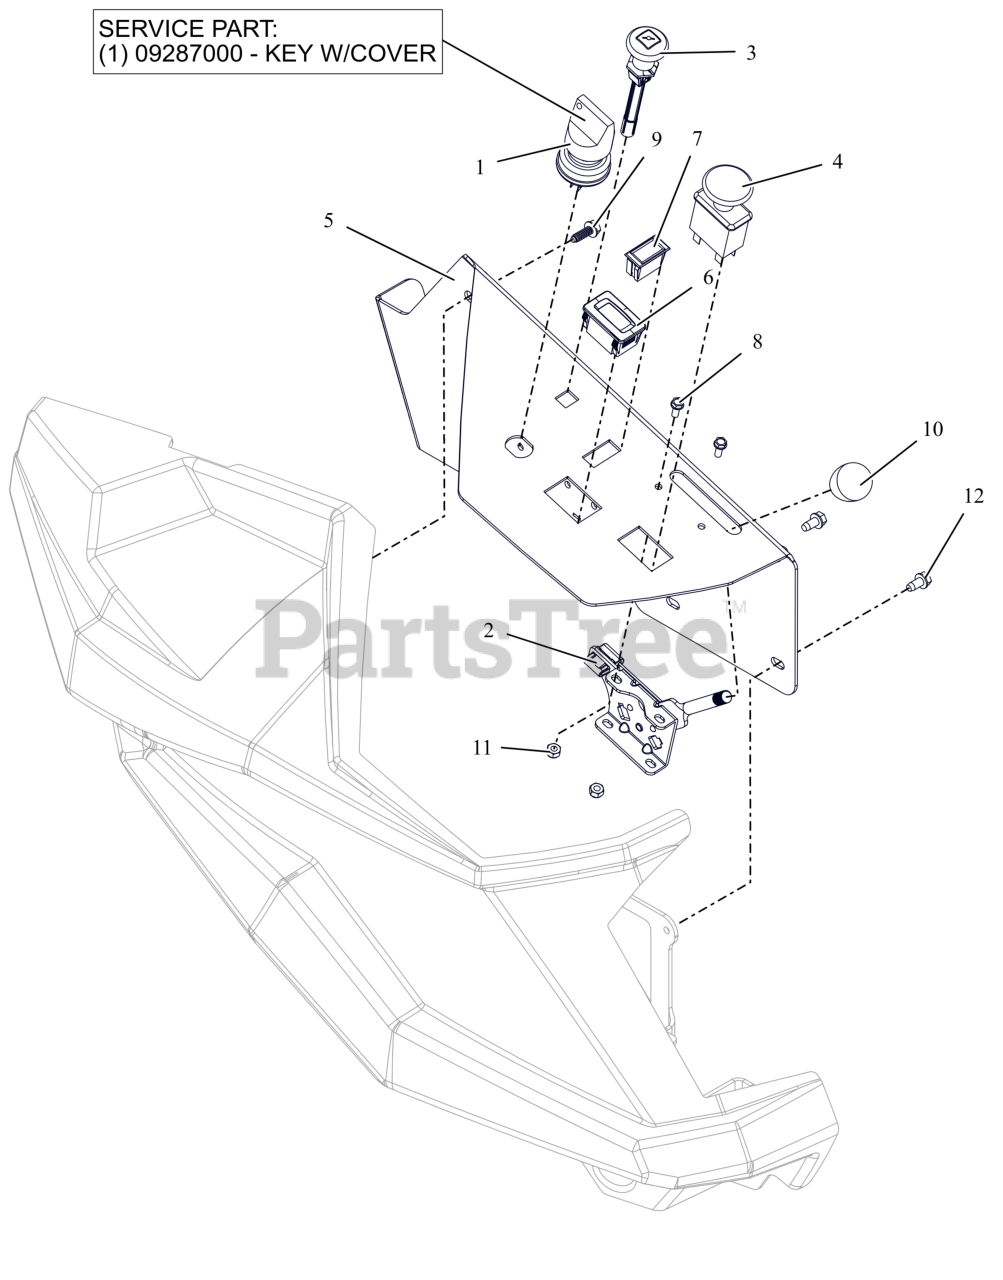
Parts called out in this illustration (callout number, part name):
1	SWITCH, IGNITION
1	KEY, W/ SHIELD
2	CABLE, PRO THROTTLE CONTROL
3	CABLE - CHOKE, SNAP-IN
4	SWITCH, CLUTCH
5	PANEL, HD CONTROL (RED)
6	HOUR METER
7	SWITCH,BLANK
8	BLT, HWH #10-24X.50 ZCC
9	SCR, PLASTITE-HWH 0.25 X 0.75 ZC120
10	KNOB-CONTROL-BLACK .38-16X.50
11	NUT-LK-NYL #10-24 G2 ZCC
12	SCR-TAP .25-20X.50 HWH ZCC
